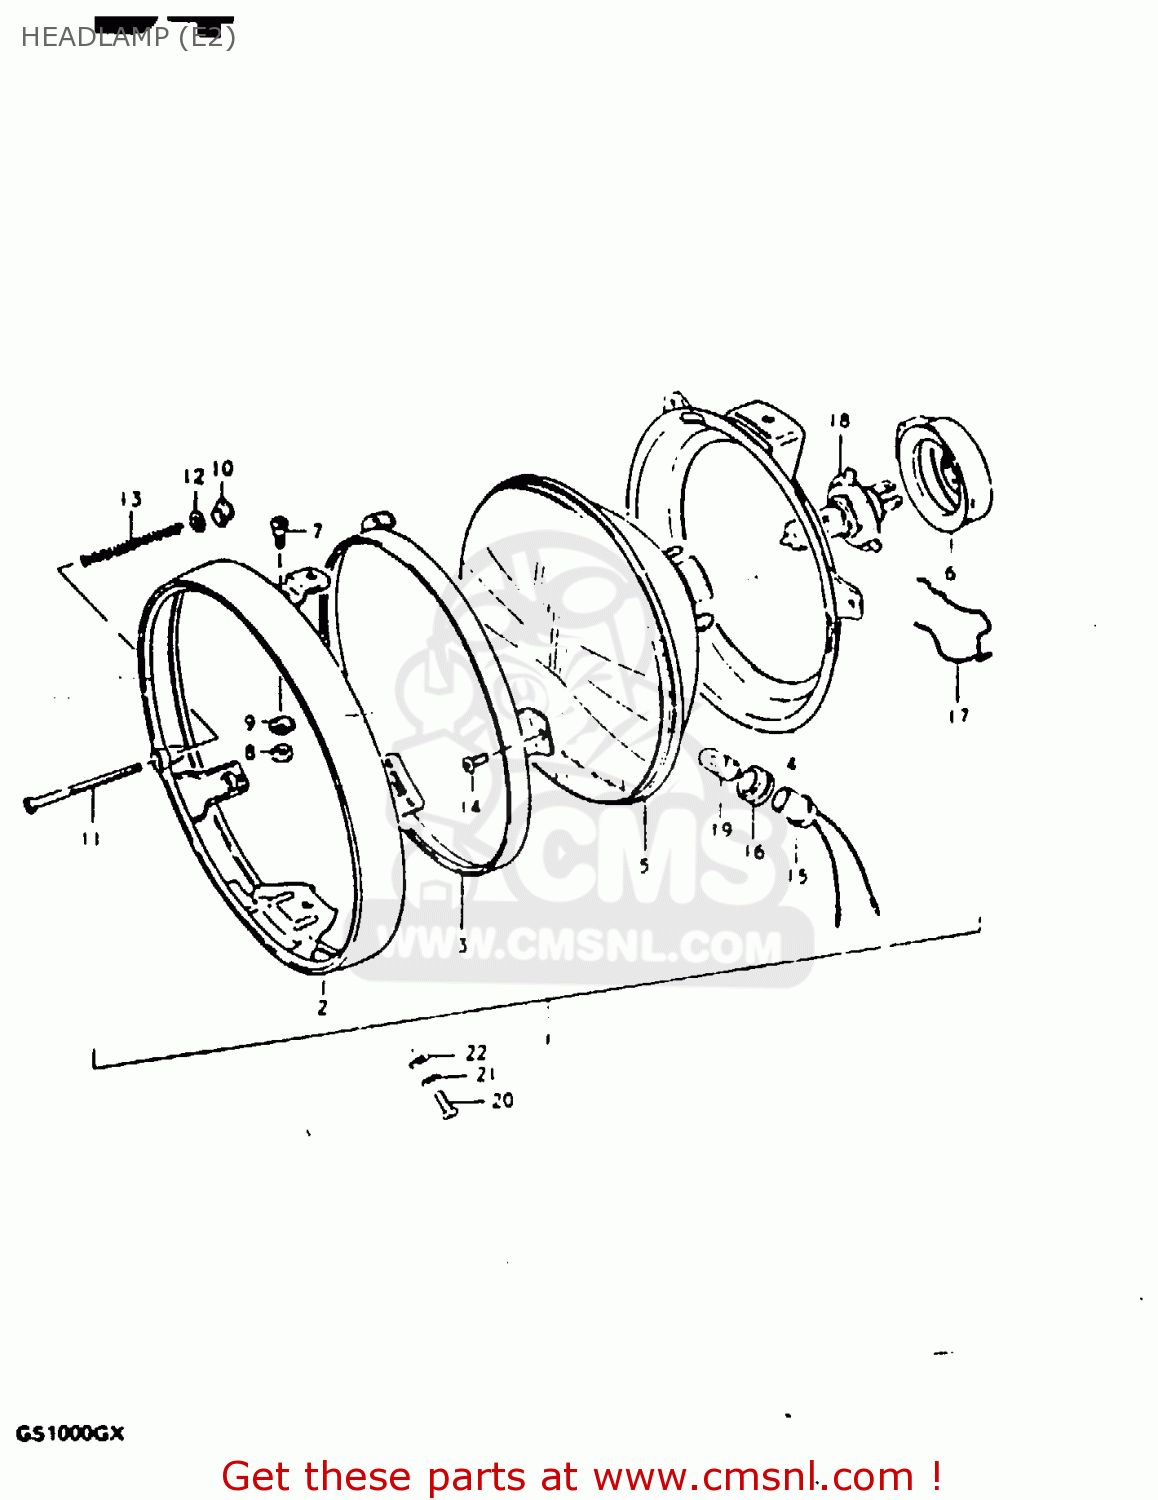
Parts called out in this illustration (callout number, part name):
1	HEADLAMP ASSY
2	RIM
3	RETAINER
4	RING,HEADLAMP UNIT
5	UNIT
6	COVER,HEADLAMP SOCKET
7	SCREW
8	NUT,ADJUSTING
9	SPACER
10	NUT
11	SCREW,HEADLAMP ADJUST
12	WASHER
13	SPRING,HEADLAMP ADJUST
14	SCREW
15	SOCKET
16	JOINT,RUBBER
17	CLAMP,HEADLAMP SOCKET
18	BULB(12V60/55W,H4)
19	BULB(12V4W)
20	SCREW
21	WASHER,LOCK
22	WASHER
